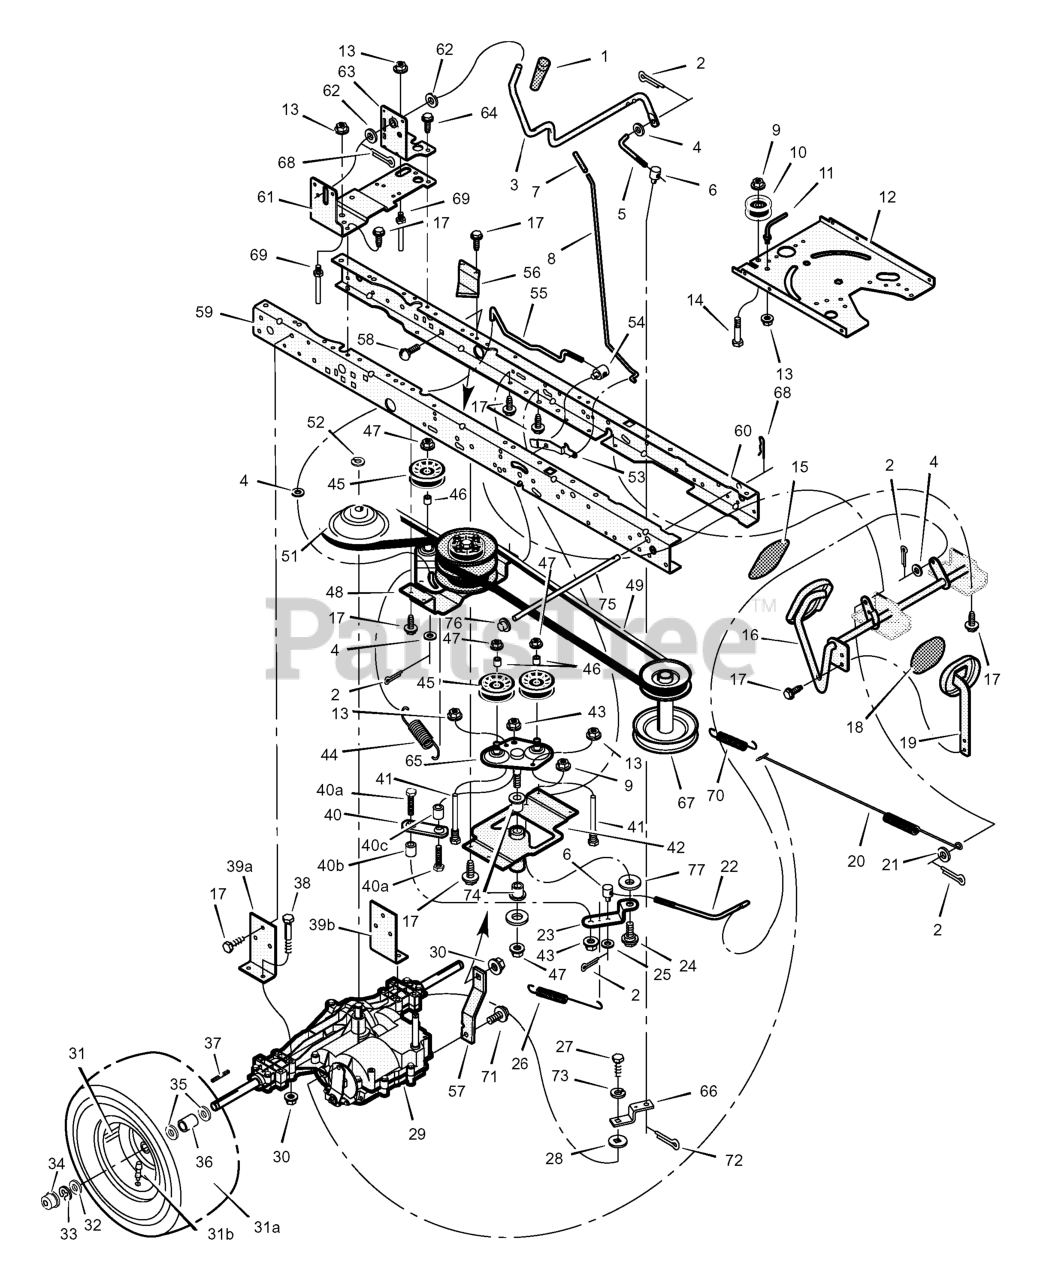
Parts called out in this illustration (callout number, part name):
1	Grip
2	Pin, Cotter
3	Lever, Shift
4	Washer
5	Link, Shifter
6	Nut, Adjuster
8	Rod, Parking Brake
9	Nut
10	Pulley, Idler
11	Guide, Belt
12	Plate, Steering
13	Nut
14	Bolt, Hex
15	Pad, Motion Drive
16	Assembly, Speed Control
17	Screw, Self Tapping
18	Pad, Brake Pedal
19	Assembly, Brake Pedal
20	Spring, Extension
21	Washer
22	Rod, Speed Control
23	Bellcrank
24	Bolt, Shoulder
26	Spring, Extension
27	Screw, Cap
29	Transaxle **
30	Nut
31	Assembly, Wheel and Tire
31B	Stem, Valve
36	Spacer
37	Key, Square
38	Bolt, Hex
39A	Bracket, Right Transaxle
39B	Bracket, Left Transaxle
40	Link, Variator
40A	Bolt, Hex
40B	Spacer, 1/2"
40C	Spacer, 3/4"
41	Guide, Belt
42	Bracket, Front Frame
43	Nut, Lock
44	Spring, Extension
47	Nut
48	Assembly, Variator and Idler
49	Belt, Primary
50	Belt, Secondary
51	Pulley, Transaxle
52	Ring, Snap
53	Latch, Parking Brake
54	Nut, Adjusting
55	Rod, Clutch
56	Bracket, Brake
57	BRACKET, Torque Strap, LH
58	Screw
59	Rail, Right Frame
60	Rail, Left Frame
61	Bracket, Right Shift
62	Washer
63	Bracket, Shift Pivot
65	Assembly, Idler
66	Yoke, Shift
67	STACK PULLEY ASSEMBLY
68	Pin, Hair
69	Guide, Belt
70	Spring, Return
72	Pin, Hair
75	Rod, Belt Guide
76	Nut, Push-On
